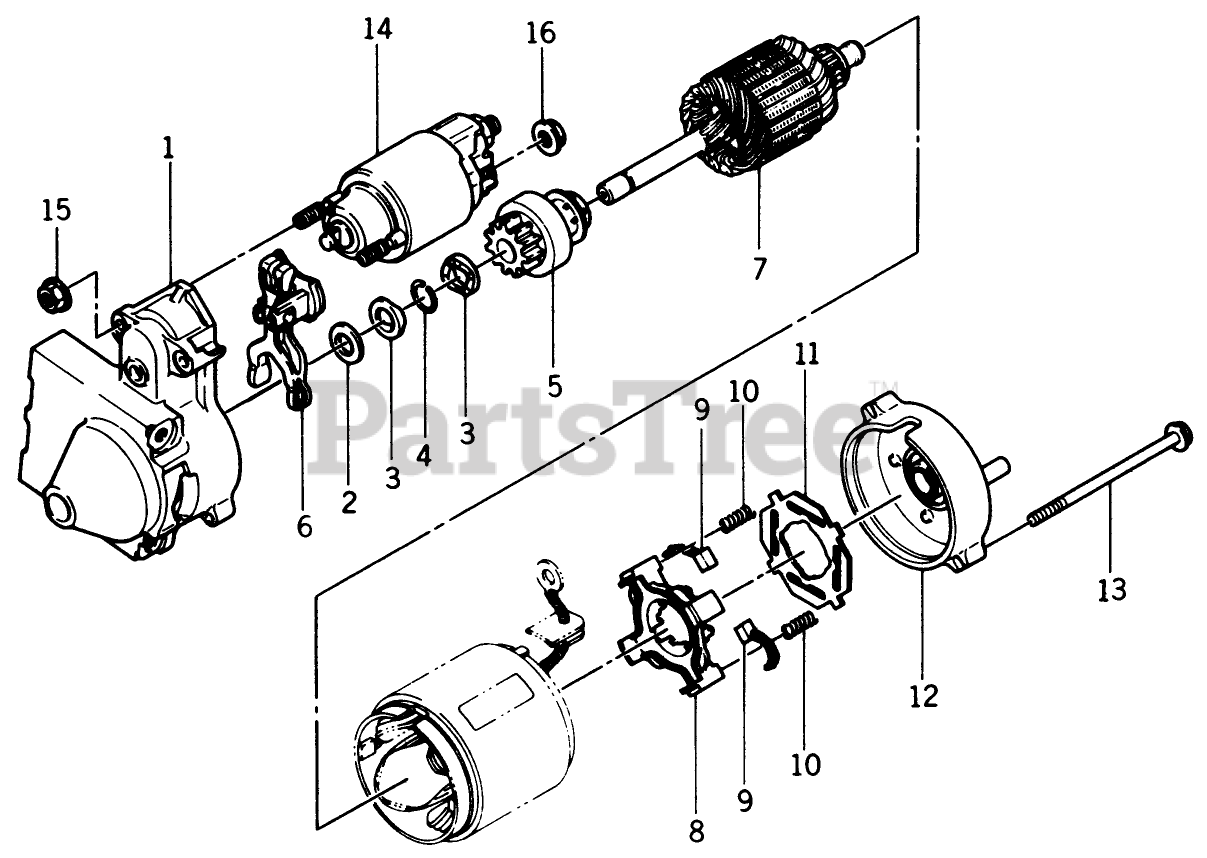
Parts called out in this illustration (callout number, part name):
1	Cover Assy
3	Stopper
4	Ring-Snap
5	Clutch Asm
6	Lever-Shift
7	Armature
8	Brush Holder
10	Spring-Brush
11	Insulator
12	Cover Assy
